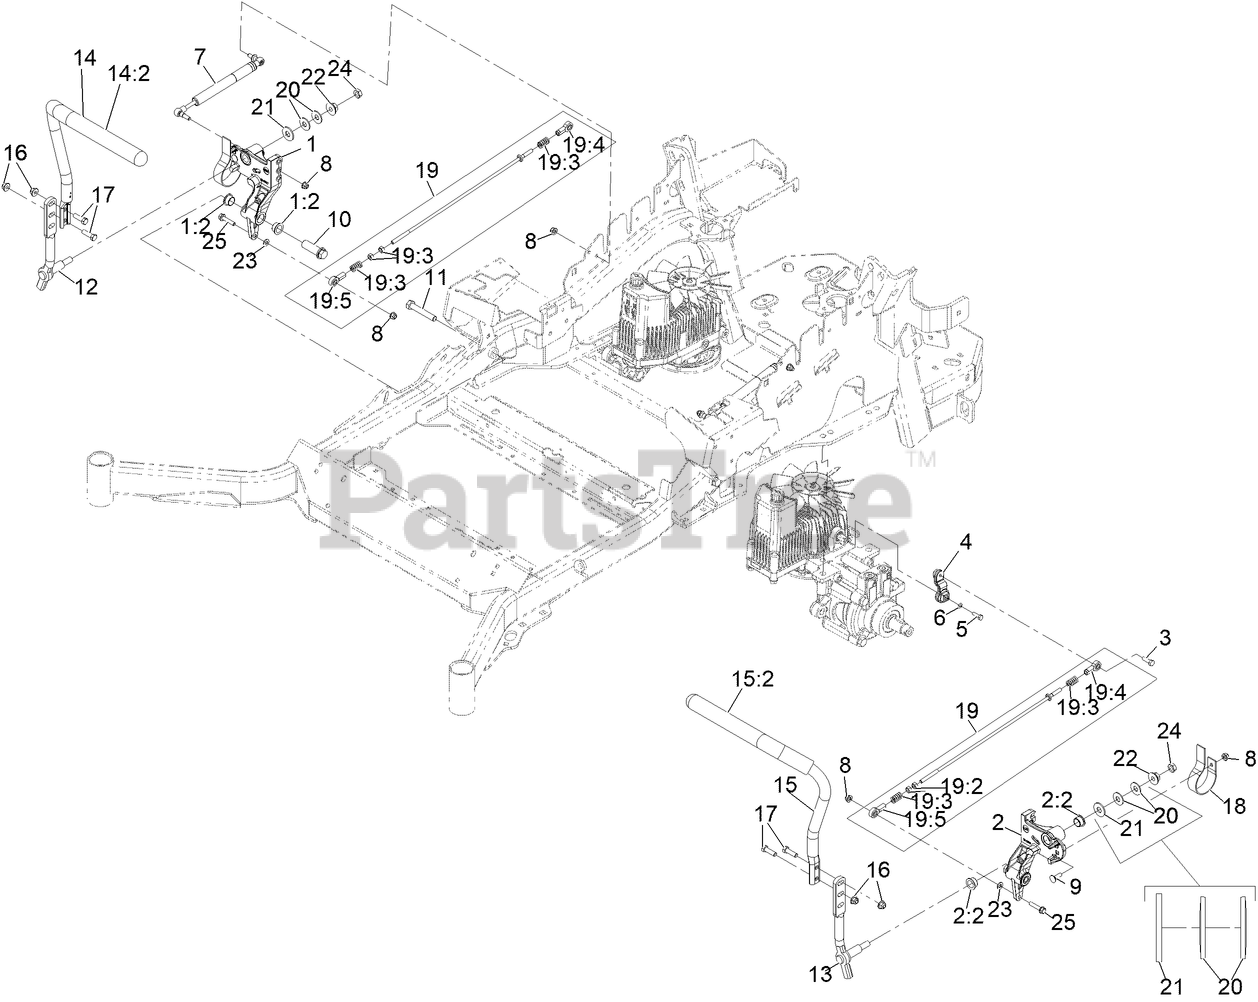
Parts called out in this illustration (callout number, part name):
1	RH MOTION CONTROL AND BUSHING ASM
1:2	BUSHING-FLANGE
2	LH MOTION CONTROL AND BUSHING ASM
2:2	BUSHING-FLANGE
3	SCREW-HH, THREAD LOCKING
4	ARM-CONTROL, PUMP
5	SCREW-HH
6	WASHER-SPRING
7	DAMPER, MOTION CONTROL
8	NUT-HF, NI
9	BOLT-CARR
10	HUB-THREADED
11	SCREW-HH
12	LEVER-CONTROL MOTION, RH
13	LEVER-CONTROL MOTION, LH
14	HANDLE- RH W/GRIP
14:2	GRIP-CONTROL, LEVER
15	ASM-HANDLE-LH
15:2	GRIP-CONTROL, LEVER
16	NUT-HF, NI
17	SCREW-HH
18	SPRING-LEAF
19	FRONT PUMP LINKAGE ASM
19:2	NUT-HEX
19:3	SPRING-COMPRESSION
19:4	BALLJOINT-LH
19:5	BALLJOINT-RH
20	WASHER-SPRING
21	WASHER-FLAT
22	NUT-HF
23	WASHER-PLAIN
24	NUT-JAM
25	SCREW-HHF
